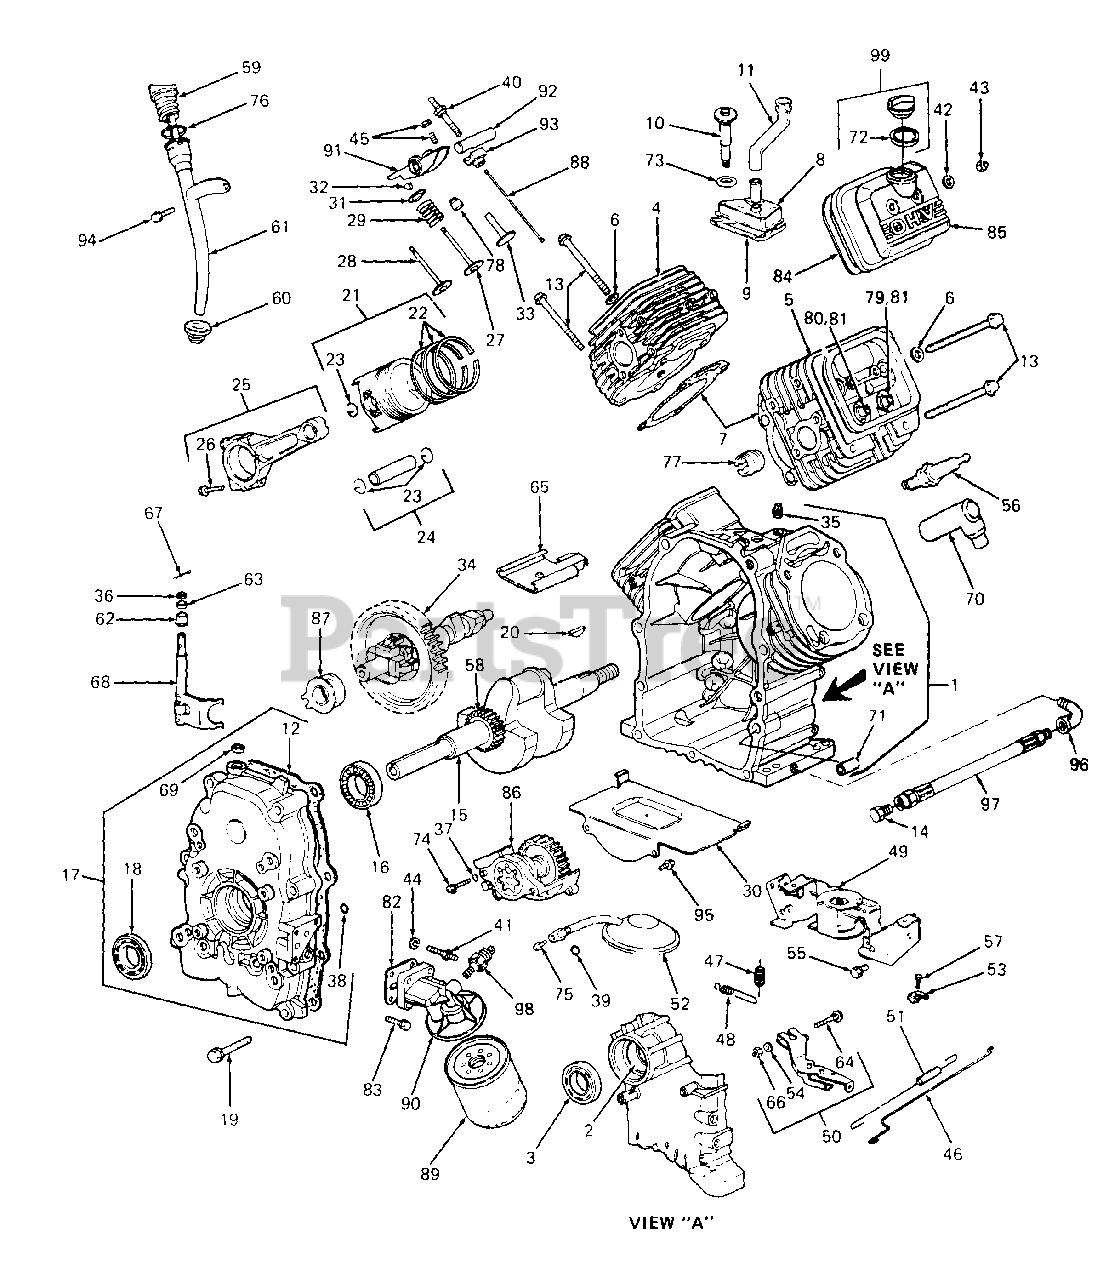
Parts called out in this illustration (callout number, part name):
1	Cylinder Assy
3	Seal, Oil
4	Head, Cylinder (Cylinder #1)
5	Head, Cylinder (Cylinder #2)
7	Gasket, Cylinder Head
8	Breather Assy
9	Gasket, Breather
10	Screw
11	Tube, Breather
12	Gasket, Cover
13	Screw
14	Plug, Oil Drain
15	Crankshaft
16	Bearing, Ball
17	Cover, Crankcase
18	Seal, Oil
19	Screw, Cover
20	Key, Flywheel
21	Piston Assy, Std
22	Ring Set, Std
23	Lock, Piston Pin
24	Pin Assy, Piston
25	Rod Assy
26	Screw, Rod
27	Valve, Exhaust
28	Valve, Intake
29	Spring, Valve
30	Plate, Windage
31	Retainer, Valve Spring
32	Retainer
33	Valve, Tappet
34	Gear, Cam
35	Plug, Pipe
36	Seal, Governor Shaft
37	O-Ring
39	O-Ring
41	Stud, Adapter
42	Washer
43	Nut, Nylock
44	Lockwasher
45	Screw, Adjustment
46	Link, Governor
47	Spring, Governor
48	Spring, Idle
49	Bracket, Governor
50	Lever Assy
51	Spring, Governor Link
52	Screen, Pick-Up
53	Clamp, Casing
55	Screw, Sems
56	Plug, Spark
57	Screw, Hex Hd
58	Gear, Timing
59	Dipstick
60	Seal
61	Tube, Filler
65	Baffle, Breather
66	Nut, Hex
67	Pin, Cotter
68	Fork, Governor
69	Washer
70	Elbow, Spark Plug
72	Seal, Fill Plug
73	Seal, Screw
74	Screw, Sems
75	Screw, Mounting
76	O-Ring
77	Liner, Exhaust Port
78	Seal, Valve Guide
79	Seat, Intake Valve
80	Seat, Exhaust Valve
81	Guide, Valve
82	Gasket, Adapter
83	Screw, Sems
84	Gasket, Valve Cover
85	Cover, Valve LH
86	Oil Pump Assy
87	Slider, Governor
88	Rod, Push
89	Filter, Oil
90	Adapter, Filter
91	Arm, Rocker
94	Screw, Mounting
95	Screw, Sems
96	Elbow, 90 Deg
97	Hose, Oil Drain
98	Switch, Oil Pressure
99	Plug, Oil Fill
